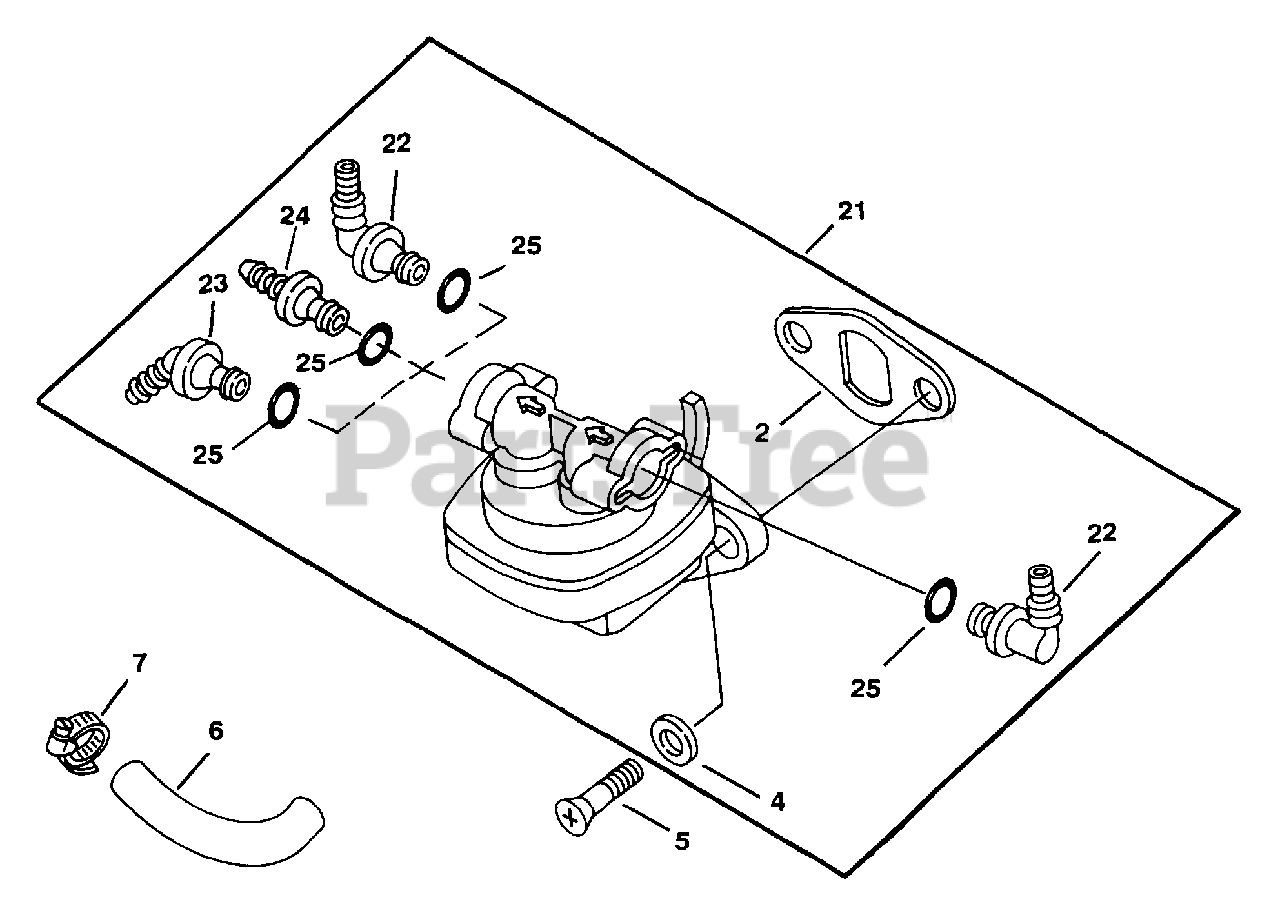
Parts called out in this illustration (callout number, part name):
4	WASHER, FLAT 1/4" (O.D. 1/2")
5	SCREW, SEMS 1/4-20X3/4"
6	LINE - DISCONTINUED
7	CLAMP, HOSE 1/2" USE 25 237 14-S
21	PUMP - USE 41 559 02
23	CONNECTOR, 45 DEG. W/O-RING
24	CONNECTOR,STRAIGHT W/O-RING-DISC.
25	CONNECTOR,STRAIGHT W/O-RING-DISC.
